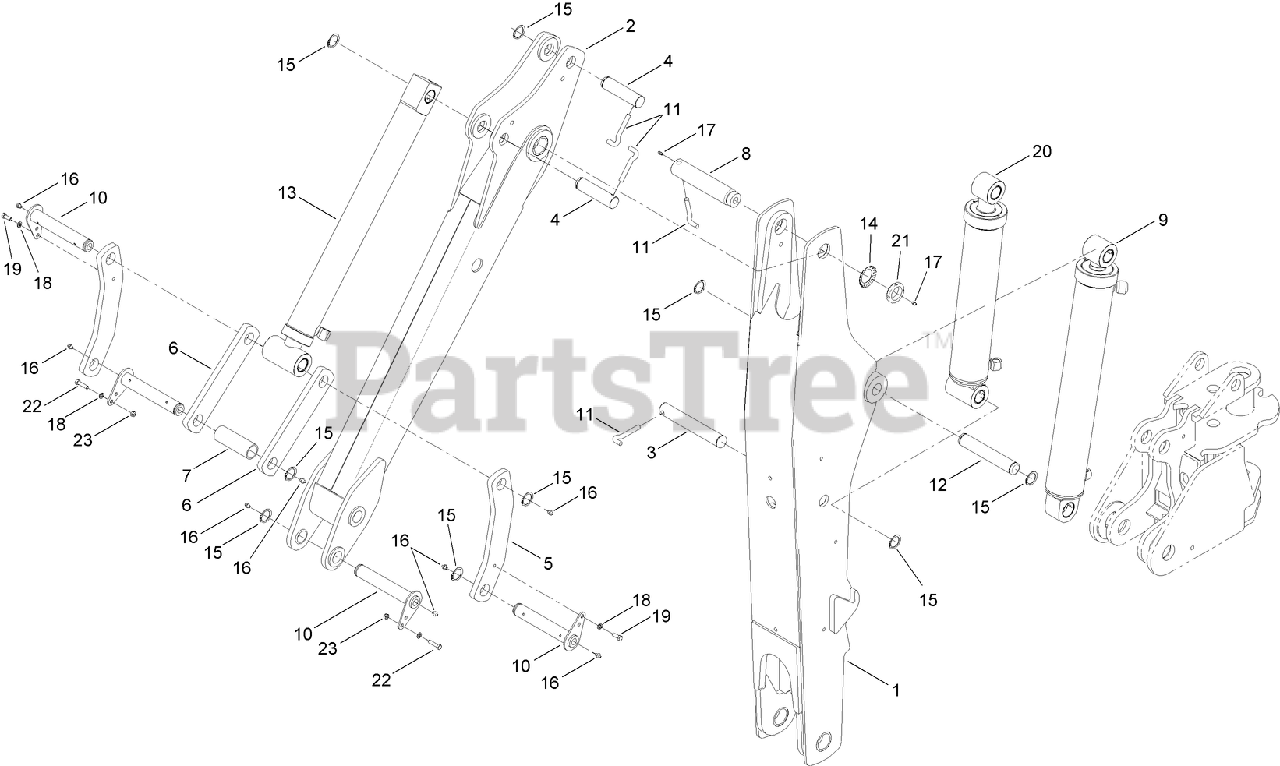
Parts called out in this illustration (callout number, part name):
2	DIPPER ASM
3	PIN-DIPPER (CYLINDER TO BOOM PIN)
4	PIN (DIPPER CYLINDER)
5	LINK-CURVED, BUCKET
6	LINK-STRAIGHT, BUCKET
7	SPACER-LINK, BUCKET
8	PIN (DIPPER PIVOT)
9	HYD CYLINDER ASM
10	PIN-BUCKET
11	PIN-RETAINER
12	PIN (STABILIZER TO FRAME)
13	HYD CYLINDER ASM
14	WASHER-BEARING, LOCK
16	FITTING-GREASE
17	FITTING-GREASE
18	WASHER-LOCK
19	SCREW-HH
20	HYD CYLINDER ASM
22	SCREW-HH
23	NUT-HEX
